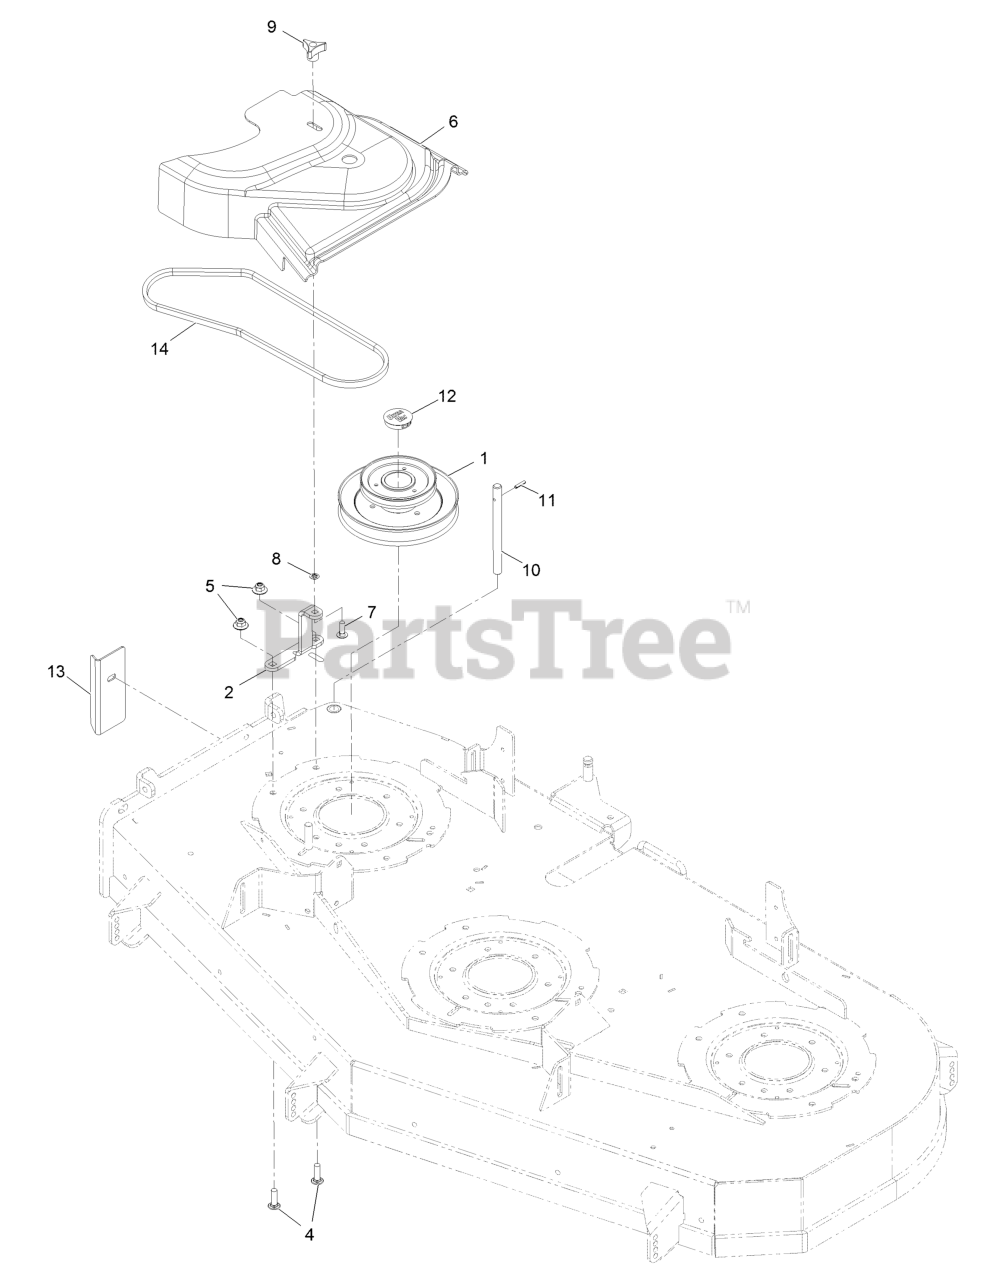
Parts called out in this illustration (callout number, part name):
1	Jackshaft,Uv Drive 604 Splined
2	Bracket-Belt Cover [black]
4	Bolt-Carriage 3/8-16 X 1 1/4
5	Nut-Nyloc 3/8-16 Flg
6	Cover-Belt Uve 60
7	Bolt-Carriage 5/16-18 X 1
8	Ring-Bolt Retaining
9	Knob-3 Prong
10	Shaft-Catcher, Grass
11	Rollpin 3/16 X 7/8
13	Plate-Blocker
14	Belt- 4L Section
